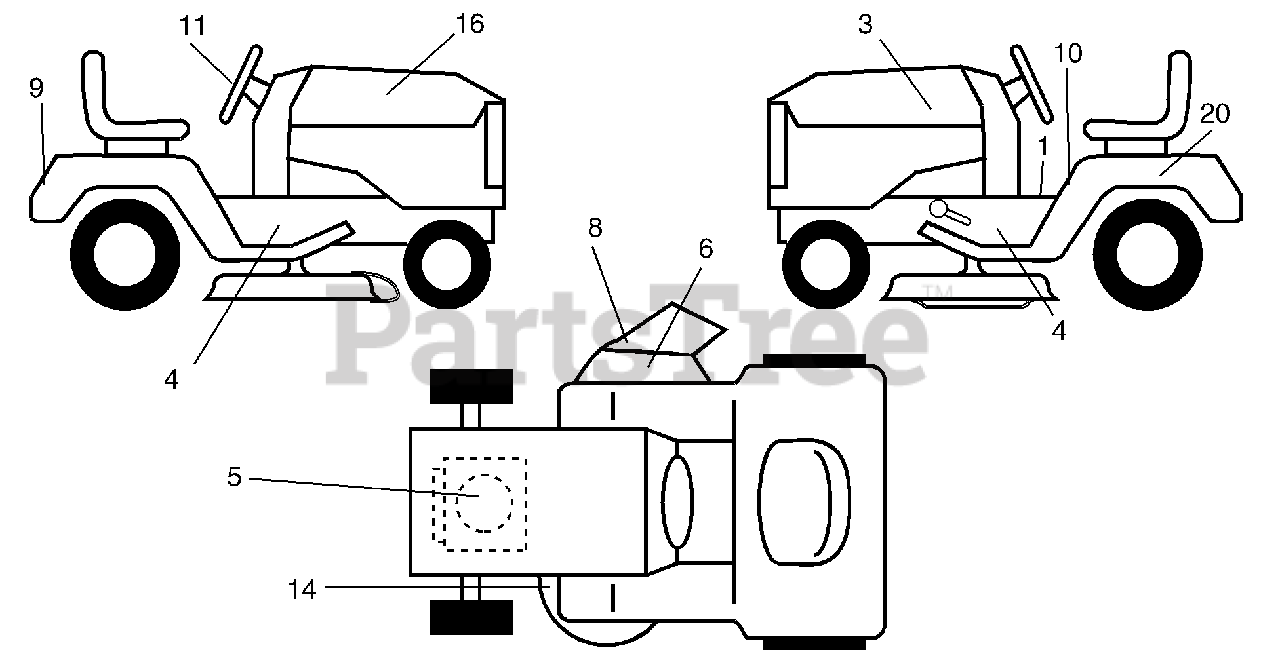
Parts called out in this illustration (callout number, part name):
1	Decal Oper
3	Decal Hood LH
4	Decal Chassis
5	Decal HP Engine
6	Decal Deck "B" 42"
7	Decal Side Panel
8	Decal Warning Mult-Language
9	Decal Fender Logo
10	Decal Fender Danger E/F
11	Decal Ins Strg Whl
14	Decal V-Belt Schematic
16	Decal Hood Rh
20	Decal Bat Dan/Psn
